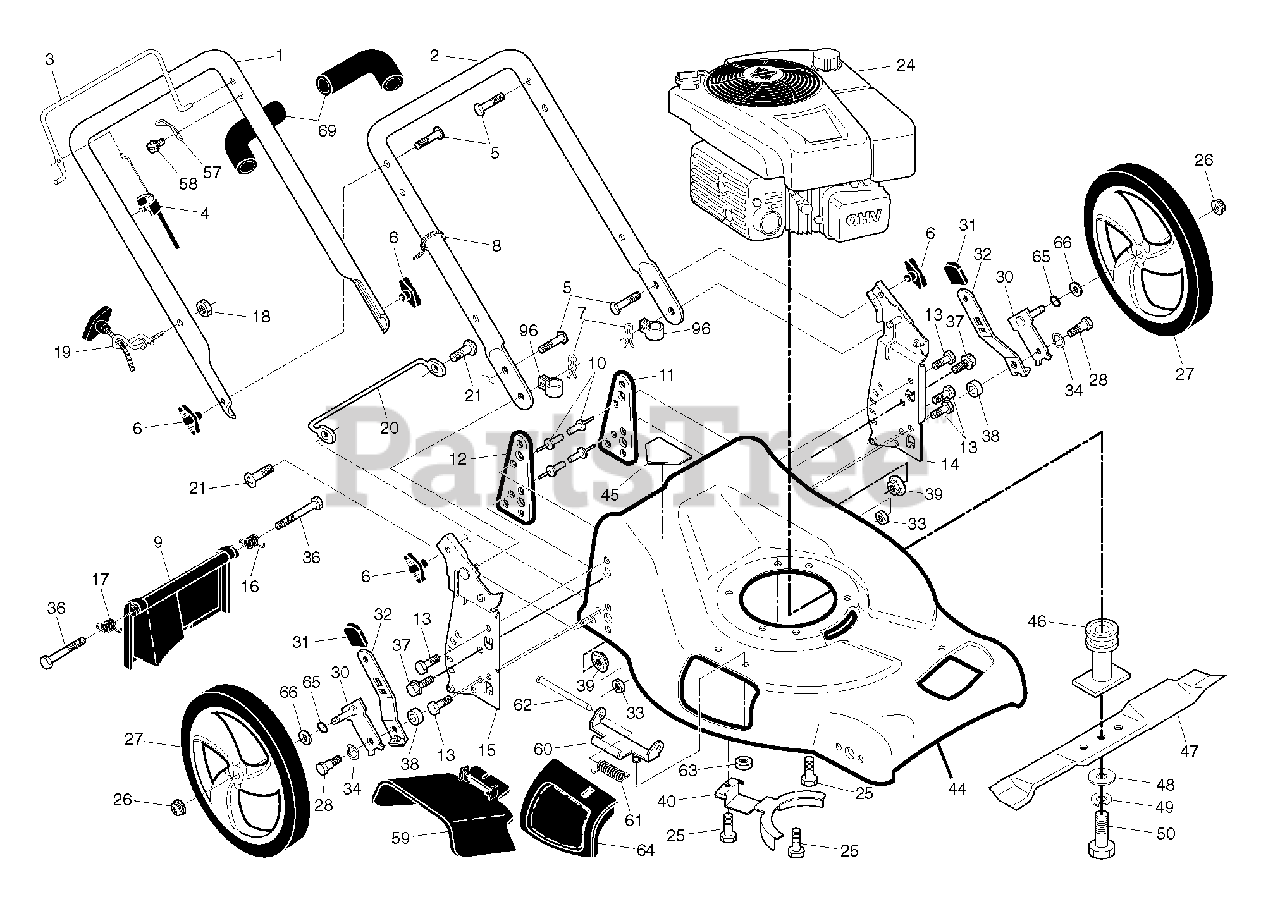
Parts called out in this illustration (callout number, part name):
2	HANDLE.LOWER.D-STRAIT.BLACK
4	CABLE.ASM.ZONE.CONTROL
5	BOLT, HANDLE 5/16-18X1.75
6	KNOB, DEFLECTOR
7	HAIRPIN COTTER
8	TIE GUIDE
9	REAR DOOR ASSEMBLY
10	RIVET BLIND
11	SUPPORT BRACKET LH
12	BRACKET.SUPRT.RH.21.FWGD
13	SCREW 14-20 X 5/8
15	BRACKET.ASM.HNDL.RT.21.FGD.HW
16	SPRING.REAR.DOOR.EZ.21.LT
17	SPRING.REAR.DOOR.EZ.21.RT
18	NUT
19	GUIDE.ROPE.STD.BLK.ZIN
21	SCREW
25	BOLT 3/8-16X1-1/8
26	NUT.HEX.FLANGE.3/8-16.LOCKNUT
28	SHOULDER BOLT 5/16-18
30	ARM.ASM.AXLE.REAR.5/9.POS.BZP
31	SELECTOR KNOB
32	SELECTOR SPRING
33	NUT.71038.31-18.HEX.NYLOCK
34	WASHER FLAT
37	BOLT
38	SPACER.HEIGHT.ADJUSTER
39	NUT.FLANGE.5/16
40	BRACKET.ENG/BELTKEEPER
45	DECAL.INTERNATIONL.CUTFINGER
47	BLADE.21.PUSH
48	WASHER,HARDEN
49	LOCKWASHER
50	SCREW, HEX HD 3/8-24 X 1-3/8
57	BRACKET.UPSTOP.RT
59	DISCHARGE DEFLECTOR
60	HINGE BRACKET ASSEMBLY
61	SPRING.TORSION
62	ROD.HINGE.21
63	LOCKNUT
64	DOOR.MULCH.21.REAR
65	O-RING..070X.487.NEOPRENE
66	WASHER PM
69	GRIP.HANDLE.FOAM.WIDE.(1 SIDE)
96	CLIP.CABLE.BLK
98	BOLT
